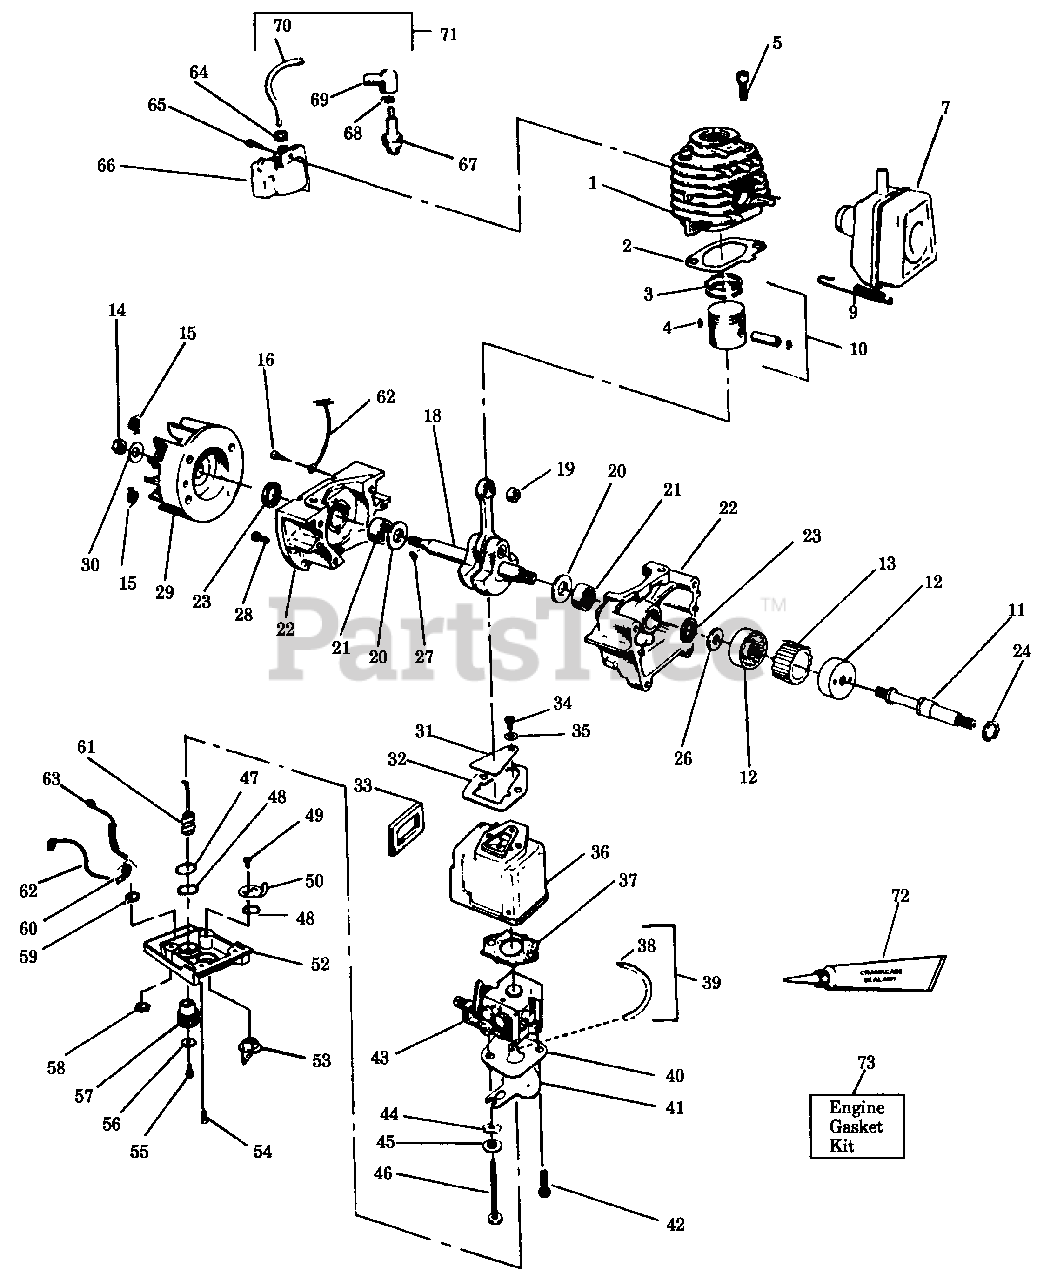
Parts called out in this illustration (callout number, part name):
1	Models 1920 & 1925
1	Model 1960
2	Cylinder Gasket
3	Models 1920, 1925
3	Model 1960
4	Wrist Pin Retainer
7	Muffler Ass'y.
9	Muffler Attachment Spring
10	Models 1920, 1925
10	Model 1960
11	Shaft Kit
12	Shaft Coupling
13	Plastic Coupling
14	Flywheel Nut
15	Starter Dog Spring
17	Piston Pin Bearing Model 1960 Only
18	Models 1920, 1925
18	Model 1960
19	Piston Pin Bearing Model 1960
21	Crankshaft Bearing
22	Crankcase Ass'y.
23	Crankcase Seal
26	Coupling Washer
27	Flywheel Key
29	Flywheel Ass'y.
30	Flywheel Washer
31	Reed Valve
32	Carburetor Case to Crankcase Gasket
33	Carburetor Case Seal
34	Screw
36	Carburetor Case
37	Carburetor Gasket
38	Fuel Line Fitting
39	Fuel Line & Fitting Ass'y.
40	Choke Guide Plate
41	Choke Shutter
43	Carburetor
44	Wave Washer
47	Retaining Ring
48	Wave Washer
50	Choke Actuator
52	Carb. Case Cover
53	Choke Knob
57	Throttle Knob
58	Grounding Switch Nut
60	Toggle Switch Kit
61	Throttle Wire Ass'y.
62	Ignition Wire
63	Ground Wire
64	Plug Wire Grommet
65	Screw
66	Ignition Module
67	Spark Plug (CJ-8)
68	Spark Plug Lead Connector
69	Spark Plug Boot
70	High Tension Lead Wire
71	High Tension Lead Ass'y.
72	Crankcase Sealant
73	Engine Gasket Kit (Inc. 23,32,33,37)
